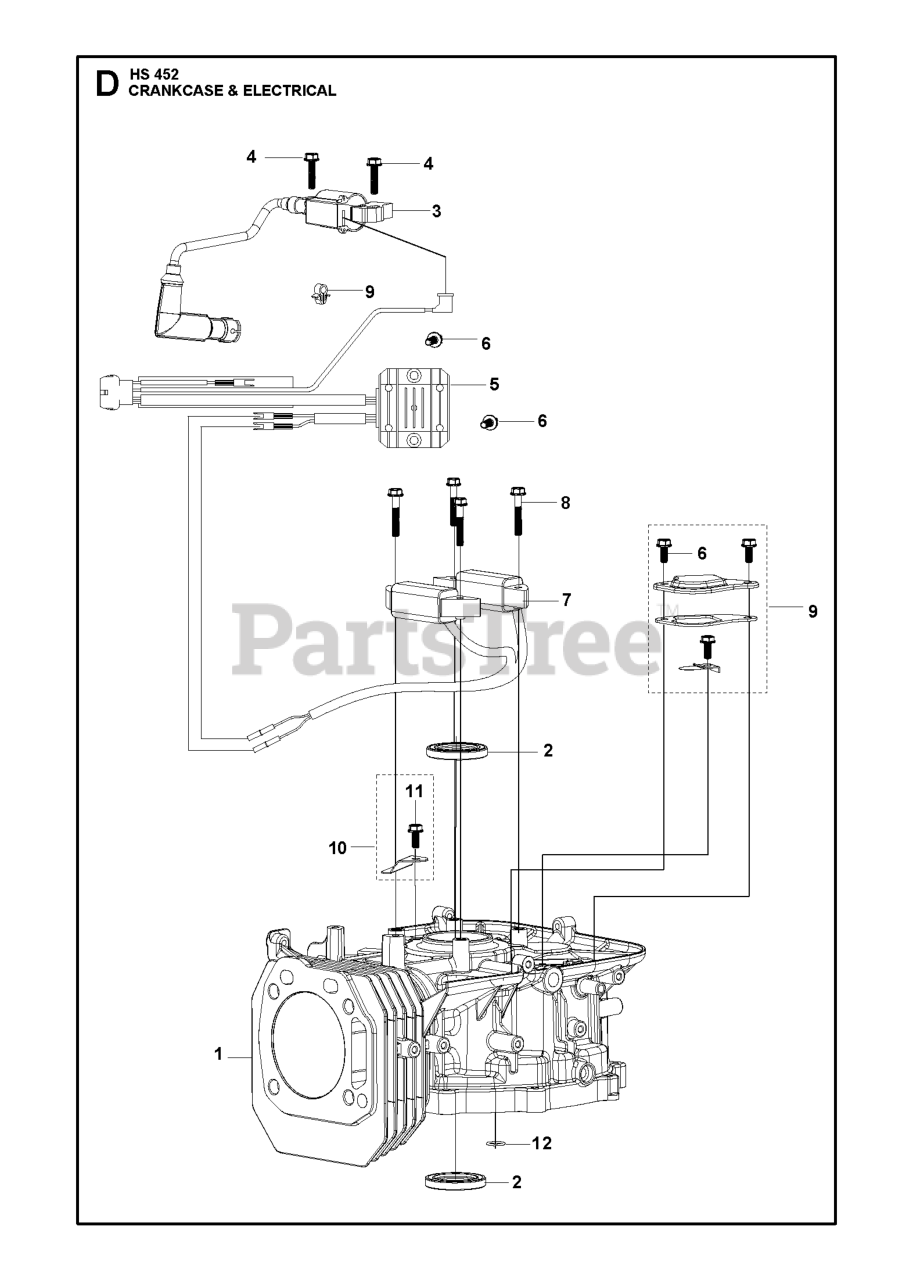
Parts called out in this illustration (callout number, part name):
2	SEAL OIL SEAL
3	IGNITION COIL
4	BOLT GB/T 5789: M6 L=25
5	VARIATOR VOLTAGE RECTIFIER KIT
6	BOLT GB/T 5789: M6 L=12
7	SERVICE KIT KIT.CHARGING AMATU
8	BOLT GB/T 5789: M6 L=30
9	BREATHER BREATHER CHAMBER KIT
10	SERVICE KIT KIT.PRESSING PLATE
11	Husqvarna TBD
12	SEALING RING SEAL RING
